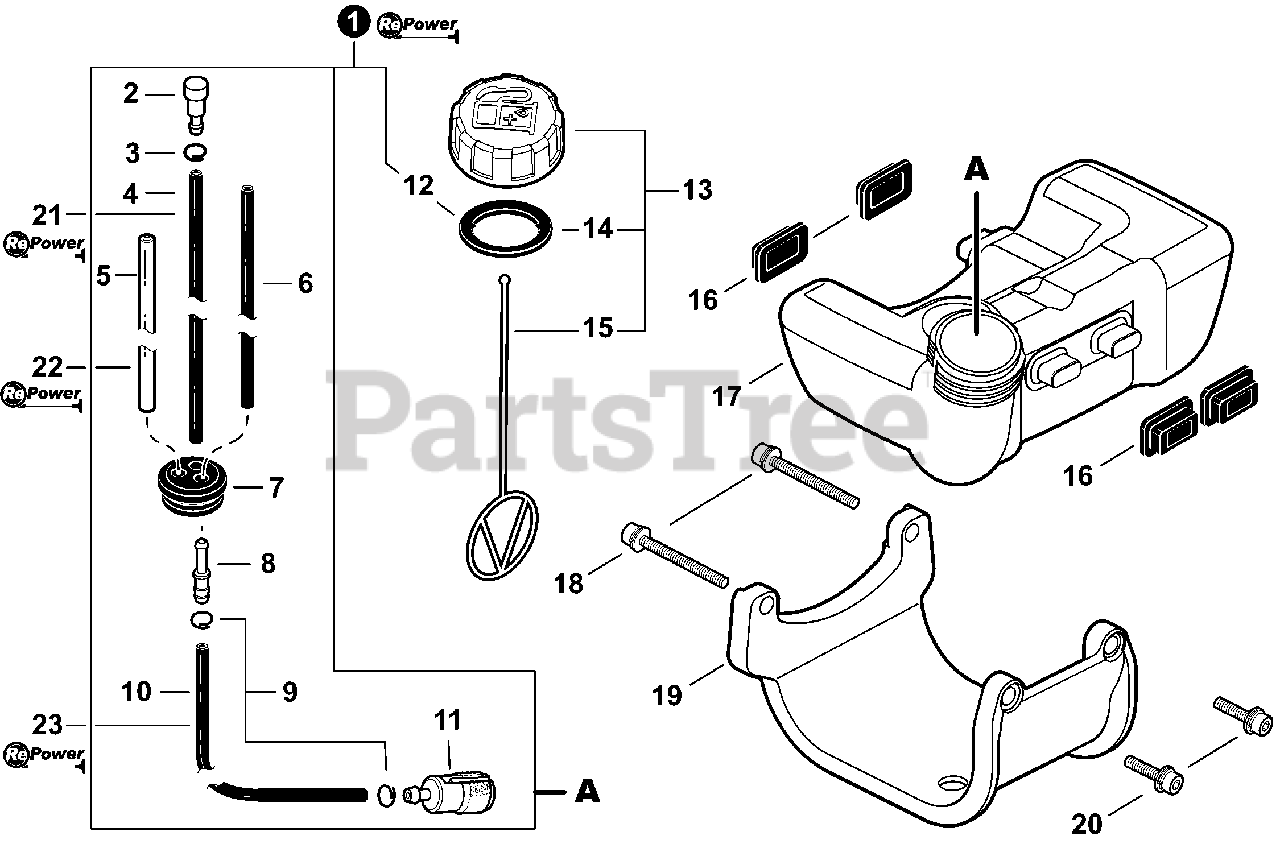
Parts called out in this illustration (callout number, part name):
1	FUEL SYSTEM KIT
2	VENT ASSY
3	CLIP Ø6.5 MM
4	PIPE, FUEL 3×6×105 BLACK
5	PIPE, FUEL 3×6×85 CLEAR
6	PIPE, FUEL 3×5×74 BLACK
7	GROMMET, FUEL
8	CONNECTOR, PIPE Ø5ר3.5
9	CLIP Ø6
10	PIPE, FUEL 3×5×140 BLACK
11	FILTER, FUEL
12	GASKET, FUEL CAP
13	CAP ASSY, FUEL
14	GASKET, FUEL CAP
15	CONNECTOR, CAP L= 123
16	CUSHION, FUEL TANK
17	TANK, FUEL
18	BOLT 5×40
19	GUARD, FUEL TANK
20	BOLT 5×18
21	BULK PIPE - 3×6 MM BLACK (4 PIECES×2 M)
22	BULK PIPE - 3×6 MM CLEAR (4 PIECES×2 M)
23	BULK PIPE - 3×5 MM BLACK (4 PIECES×2 M)
